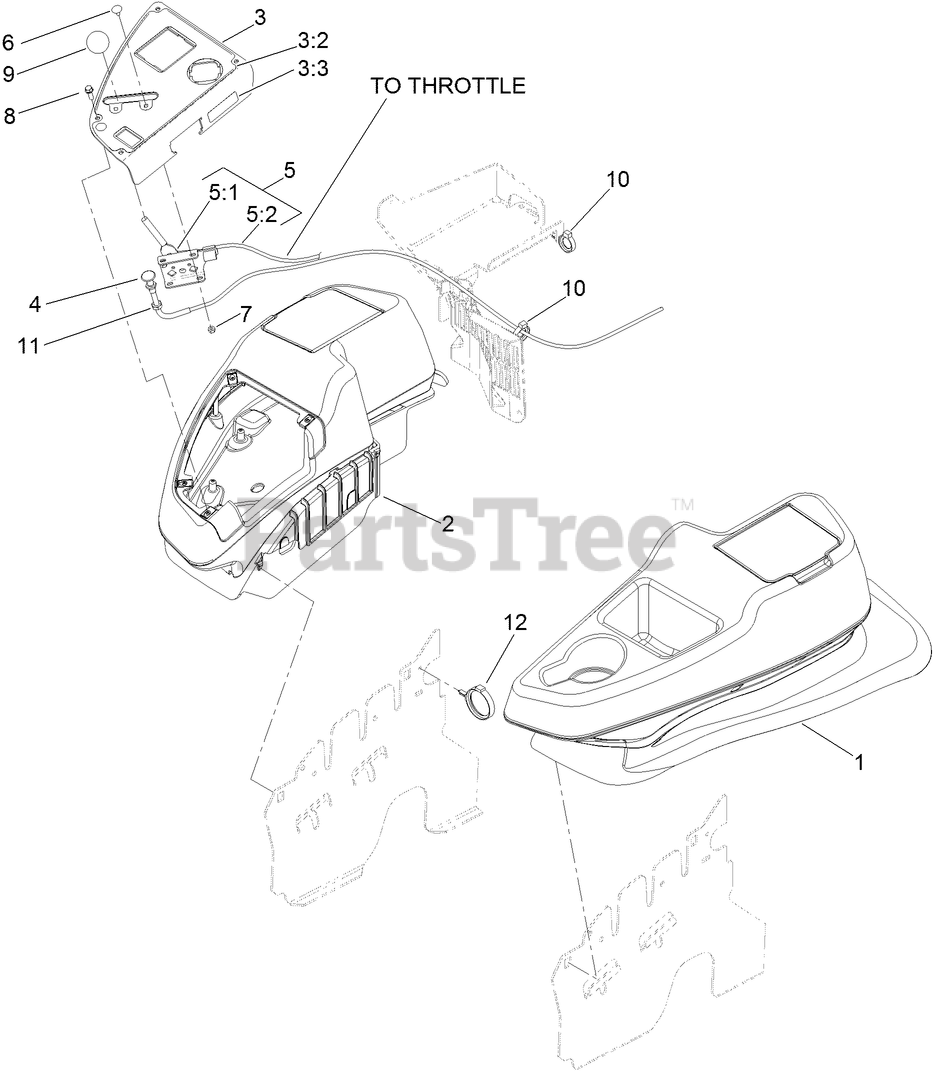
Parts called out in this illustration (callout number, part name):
1	LH CONSOLE ASM
2	RH CONSOLE ASM
3	CONTROL PANEL ASM
3:2	DECAL-PANEL, CONTROL
3:3	DECAL-FUSES
4	CHOKE CONTROL ASM
5	THROTTLE CONTROL ASM
5:1	LEVER-THROTTLE
5:2	CABLE-THROTTLE
6	BOLT-CARR
7	NUT-LOCK, NI
8	SCREW-HWH
9	KNOB-BALL
10	CLAMP-HOSE
11	NUT-HJ
12	CLAMP-HARNESS
